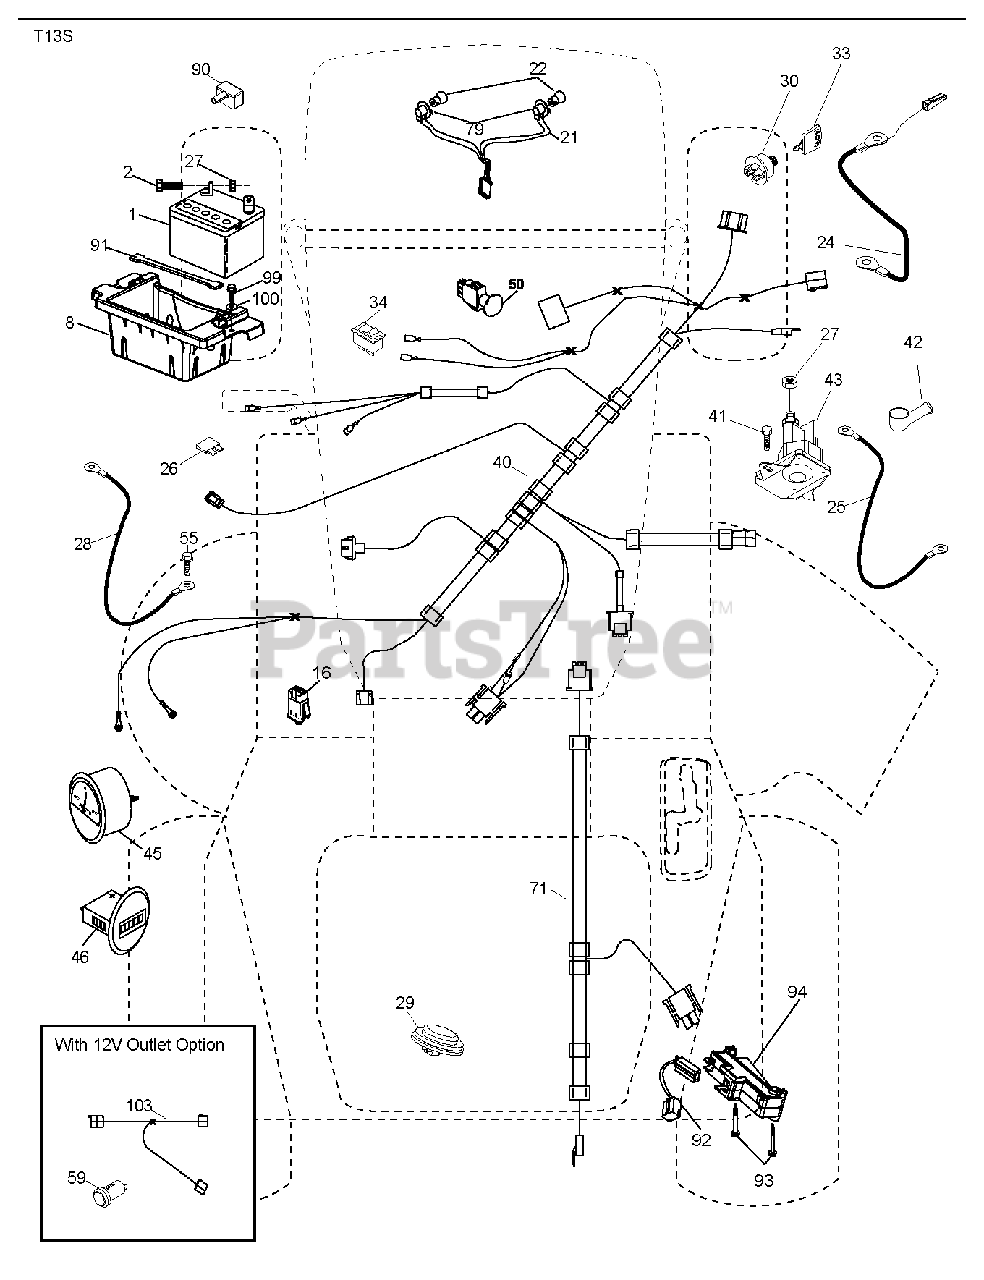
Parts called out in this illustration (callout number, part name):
1	REPL BY 532 12 38-99
8	BOX.BATTERY.MOUNT.FRONT.LT
16	SWITCH INTERLOOK PUSH-IN
21	HARNESS.LIGHT W/4152J BULBS
22	LIGHTBULB
24	CABLE.BATT.POS.WIRE.TG.DA SOL
25	CABLE.STARTER.6G.BL/RED.17.5
26	FUSE 20AMP
27	NUT
28	CABLE GROUND 6 GA 21" 90T BLK
29	SWITCH.SEAT.DELTA.OPC.
30	SWITCH.IGN.DELTA.W.LGH.ROS
33	KEY.CHAIN.BLISTER.PACK.GEN.INT
34	SWITCH LT
40	HARNESS IGN. DASH
41	SCREW
42	TERMINAL COVER
43	SOLENOID.W/BRASS.PLUNG
46	HOURMETER SNAP-IN
50	PTO SWITCH
55	SCREW 5/16"
71	HARNESS-CHASSIS SUB
79	BULB HOLDER ASM.
90	COVER.TERMINAL.BATTERY
91	STRAP, BATTERY MOUNT
92	HARNESS.PIGTAIL.CONSLE
93	SCREW.PLASTITE
94	MODULE.REVERSE.ROS
99	SCREW HEXWSHR 1/4-20X3/4
